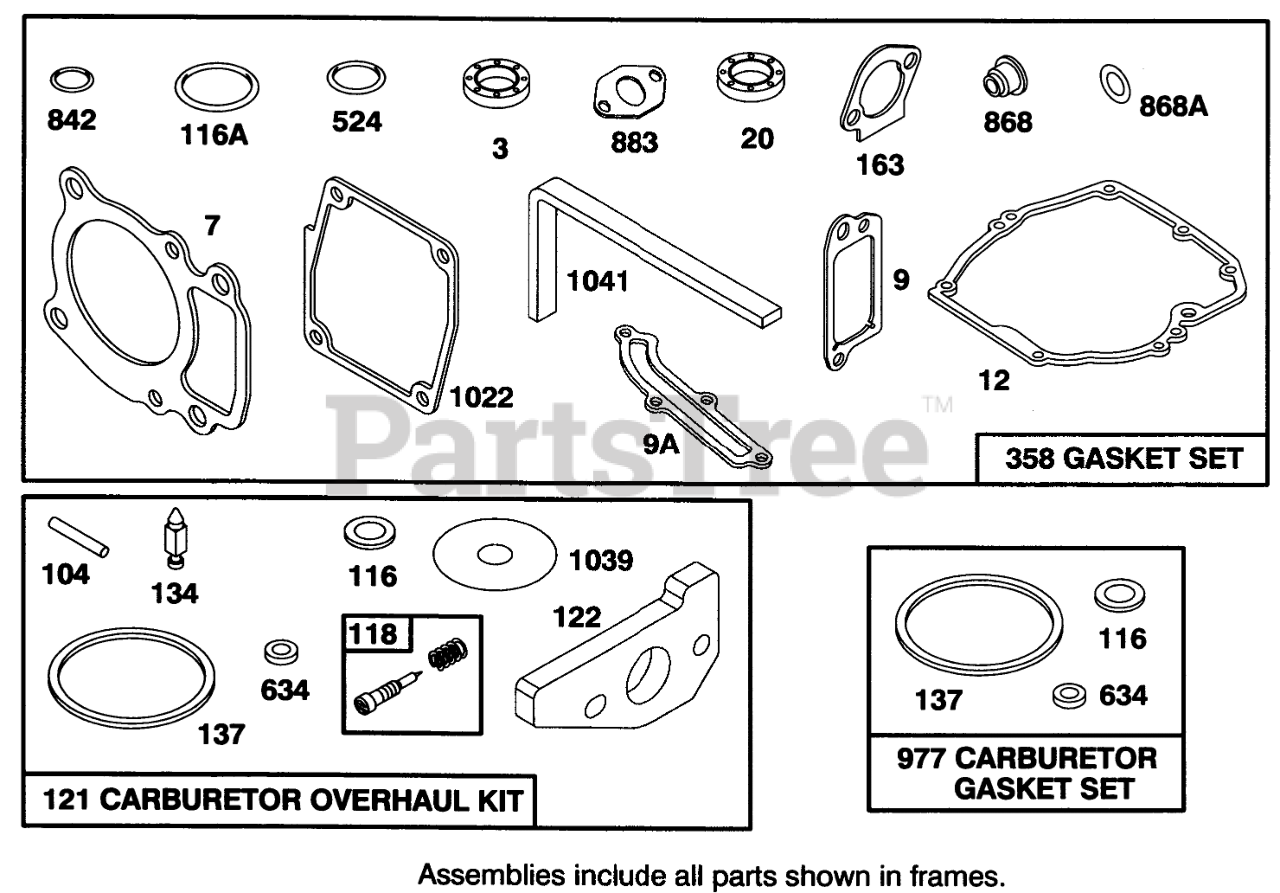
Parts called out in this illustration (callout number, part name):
3	SEAL - OIL
7	CYLINDER HEAD GASKET
9	BREATHER GASKET
9A	GASKET-BREATHER
12	ENGINE BASE GASKET
20	SEAL-OIL
104	FLOAT HINGE PIN
116	SEALING GASKET
116A	O RING SEAL
118	VALVE KIT - NEEDLE
121	CARBURATOR OVERHAUL KIT
122	ADAPTER ASSEMBLY
134	Valve-Inlet (Includes Seat)
137	FLOAT BOWL GASKET
163	AIR CLEANER GASKET
358	GASKET SET
524	O-RING
634	SEAL WASHER
842	O-RING
868	SealAssy-Valve
868A	Seal-Valve
883	EXHAUST GASKET
977	CARBURATOR GASKET SET
1022	ROCKER COVER GASKET
1039	VENT TUBE
1041	SEAL - FOAM
